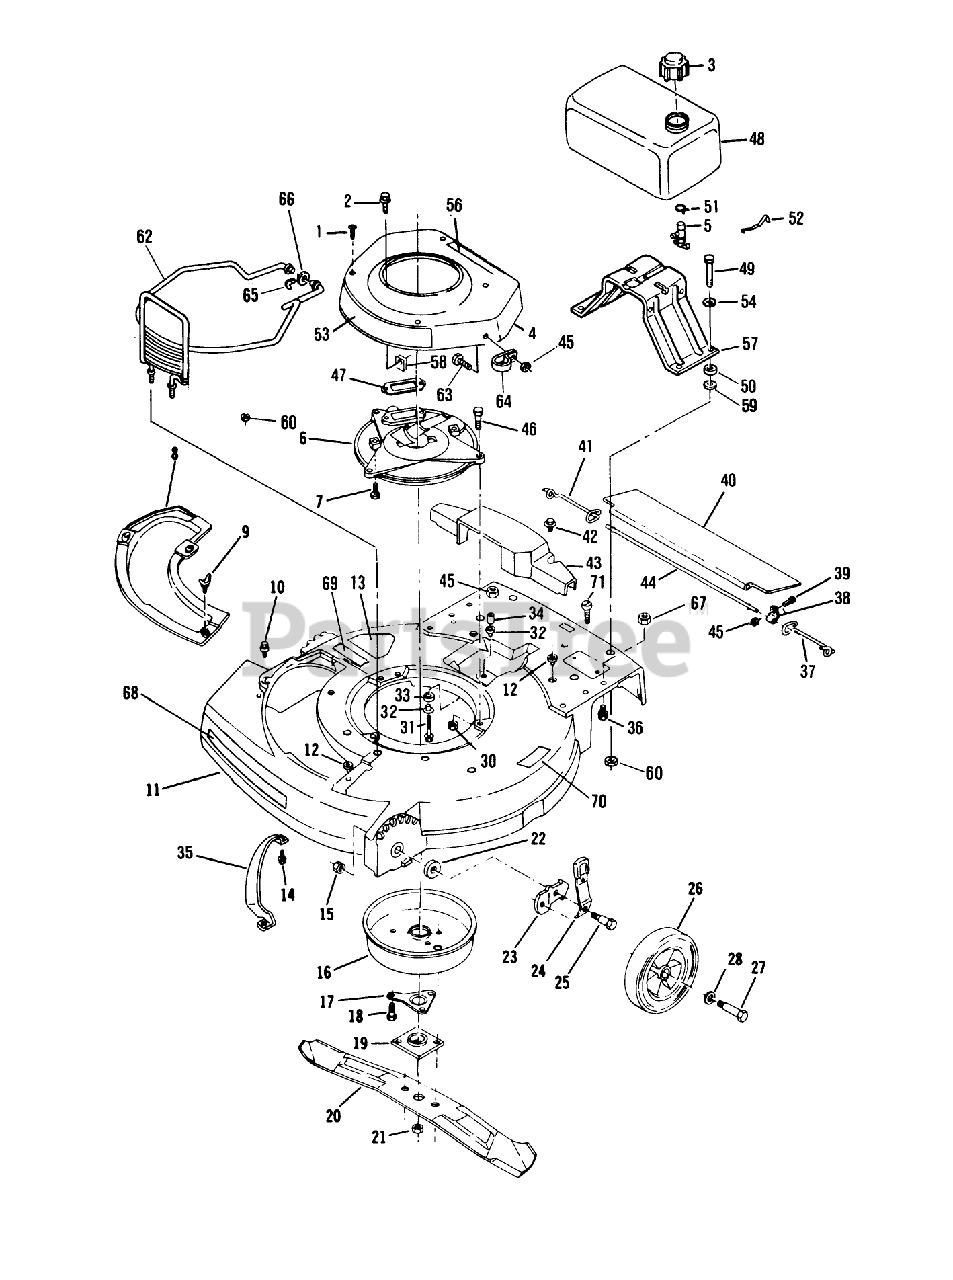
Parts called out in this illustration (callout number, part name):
1	SCREW - SELF TAPPING
2	SCREW SEMS SM
3	FUEL CAP & INSERT
5	VALVE&SCREEN SM
6	PLATE F
7	SCREW V
9	WING SCREW LAWRE
15	LOCKNUT
16	MUFFLER COVER F
17	SUPPORT F
18	SCREW
19	PLATE AND COLLAR ASM
21	NUT-BLADE
22	WASHER
24	SPRING ARM ASM
25	BOLT
26	WHEEL & TIRE ASSY
27	BOLT-SHOULDER
28	SPACER
30	NUT-LOCK F
32	SPACER ECK PRES
33	GROMMET
34	SPACER
35	BAR-TOE
37	SPRIG T/SHLD ASOC
38	CLAMP ROD KMC
40	SHIELD
41	SPRING;TRAILING SHIELD RH
42	SCREW SEMS TRM HEX HD
43	COVER
44	ROD 21" ADVANCE
45	LOCKNUT E
46	SCREW-HH
49	BOLT PIONEER
51	CLAMP - HOSE S
52	SPRING
54	WASHER
58	PUSHNUT F
59	WASHER
60	LOCKNUT E
65	HAIR PIN
66	WASHER SPRING LAR
67	NUT-LOCK F
